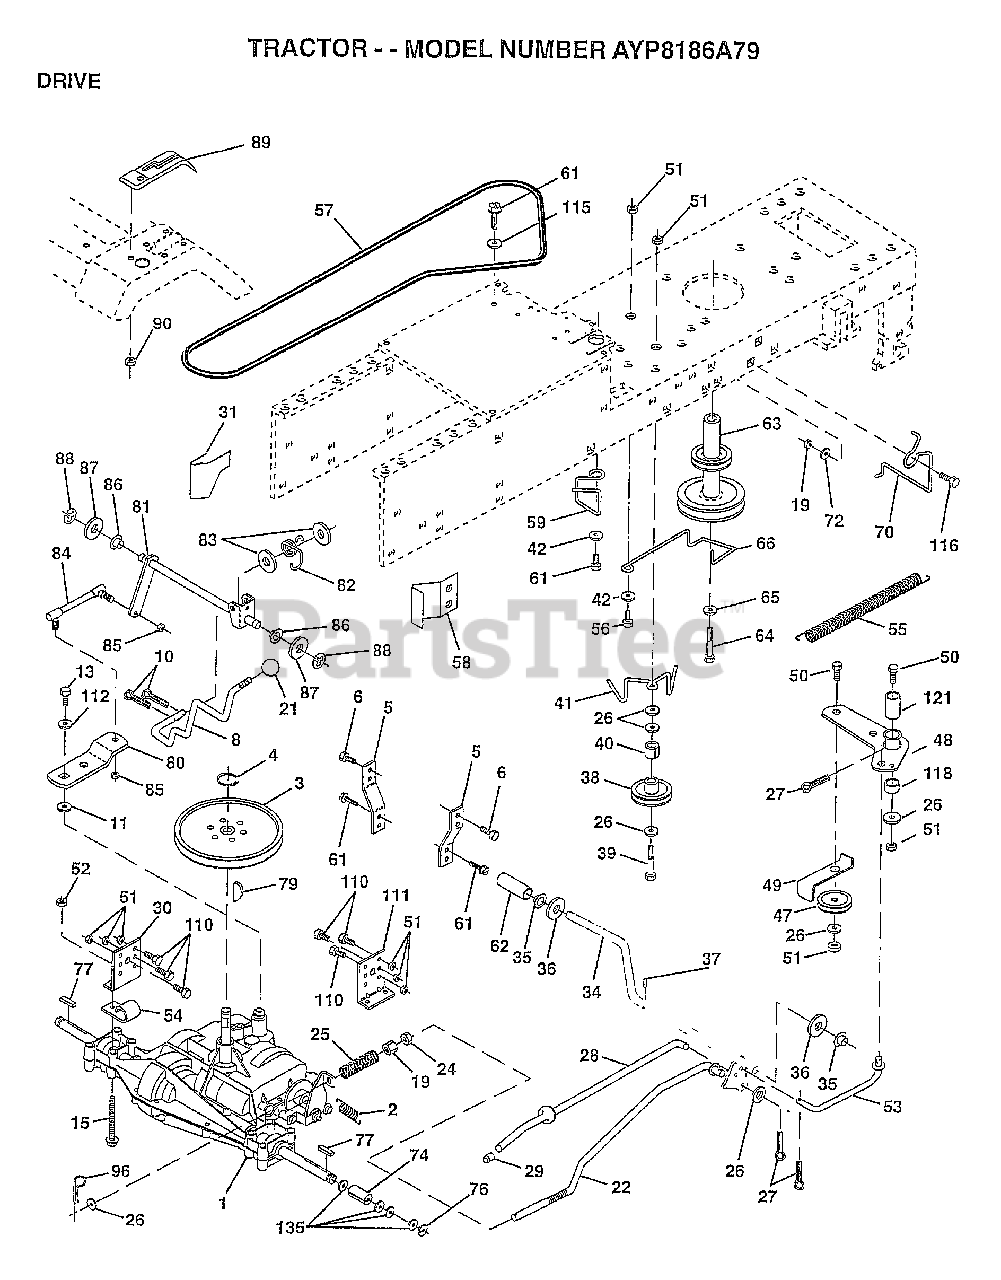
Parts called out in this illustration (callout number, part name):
3	PULLEY TRANSAXLE
5	STRAP TORQUE
6	SCREW
8	ROD SHIFT FEND YT
10	PIN COTTER 1/8
11	WASH-SHFT PLT LT
13	BOLT.1/4-28.W/PAT
19	NUT
21	KNOB T (1/2-HOLE)
22	ROD.ASM.BK.44.MWR
24	NUT
25	"SPRING,ROD BRAKE"
26	WASHER
27	COTTER PIN
28	ROD.BRAKE.PARK.LT
30	BRKT TRANS LH
31	KEEPER BELT LH
34	SHAFT ASM-PEDAL F
35	NYLON BEARING
36	WASHER LT
38	PULLEY.IDLER.FLAT
39	BOLT
40	SPACER T
42	WASHER
48	BELLCRANK ASM
49	RETAIN BELT
53	"LINK, CLUTCH T"
54	"CLIP,INSULATOR"
55	"SPRING, RETURN LT"
57	BELT.GRDRV.94.75
58	"KEEPER,BELT RH"
59	KEEPER BELT CNTSP
61	SCREW
62	PEDAL COVER T
64	BOLT
65	LOCKWASHER
66	KEEPER-BELT
70	"GUIDE.BELT,RH ENG"
72	WASHER
74	SPACER HYT
76	E RING HYT
77	SQ KEY STD
80	"ARM,SHIFT"
81	"SHAFT,SHIFTER"
82	"SPRING,TORSION"
83	WASHER
84	"ROD LINK,SHIFT AD"
85	NUT.CNT.LOCK.1/4
86	BUSHING
87	WASHER D
88	KLIP RING
89	CONSOLE SHIFTER
90	NUT
96	RETAINER M
100	WASHER M
102	WASHER BELLEVILLE
111	BRKT TRANS RH
112	WASHER PM
115	WASHER GT
116	BOLT RDHD 3/8-16
118	SPACER-BELLCRANK
121	NYLINER-CLUTCHING
135	WASHER
137	WASHER
138	WASHER
139	BOLT
